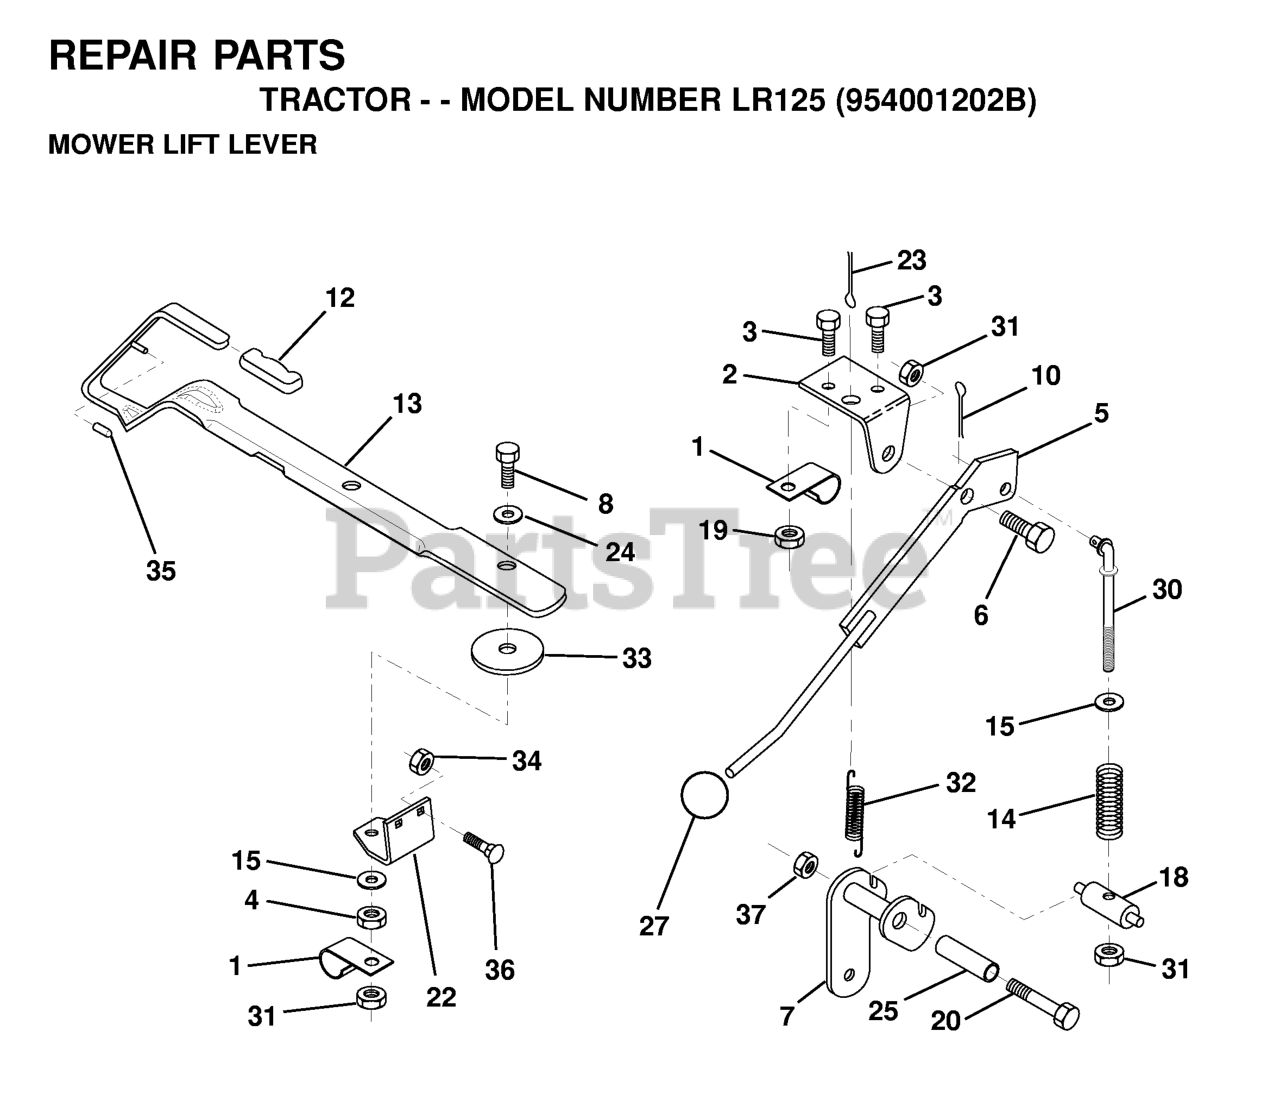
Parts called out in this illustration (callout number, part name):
1	CLIP,INSULATOR
2	BRKT CLUTCH
3	BOLT
4	LOCKNUT
6	BOLT, SHOULDER LT
7	CLUTCH ARM ASMBLY
8	Bolt, Hex Head 3/8-16 UNC x 1-1/2
10	COTTER PIN
12	GRIP HANDLE
13	LIFT LEVER ASM
14	COMP. CLUTCH SPRING
15	WASHER
19	NUT.CROWNLOCK.1/4
22	LIFT LEVER BRACKET
23	COTTER PIN
25	TUBE SPACER
30	TENSION ROD CLUTCH
31	NUT
32	SPRING EXT
34	NUT.71038.31-18.HEX.NYLOCK
35	CAP.VINYL.RED
36	RP BOLT 5/16-18 X3/4 ZN/YEL GR
